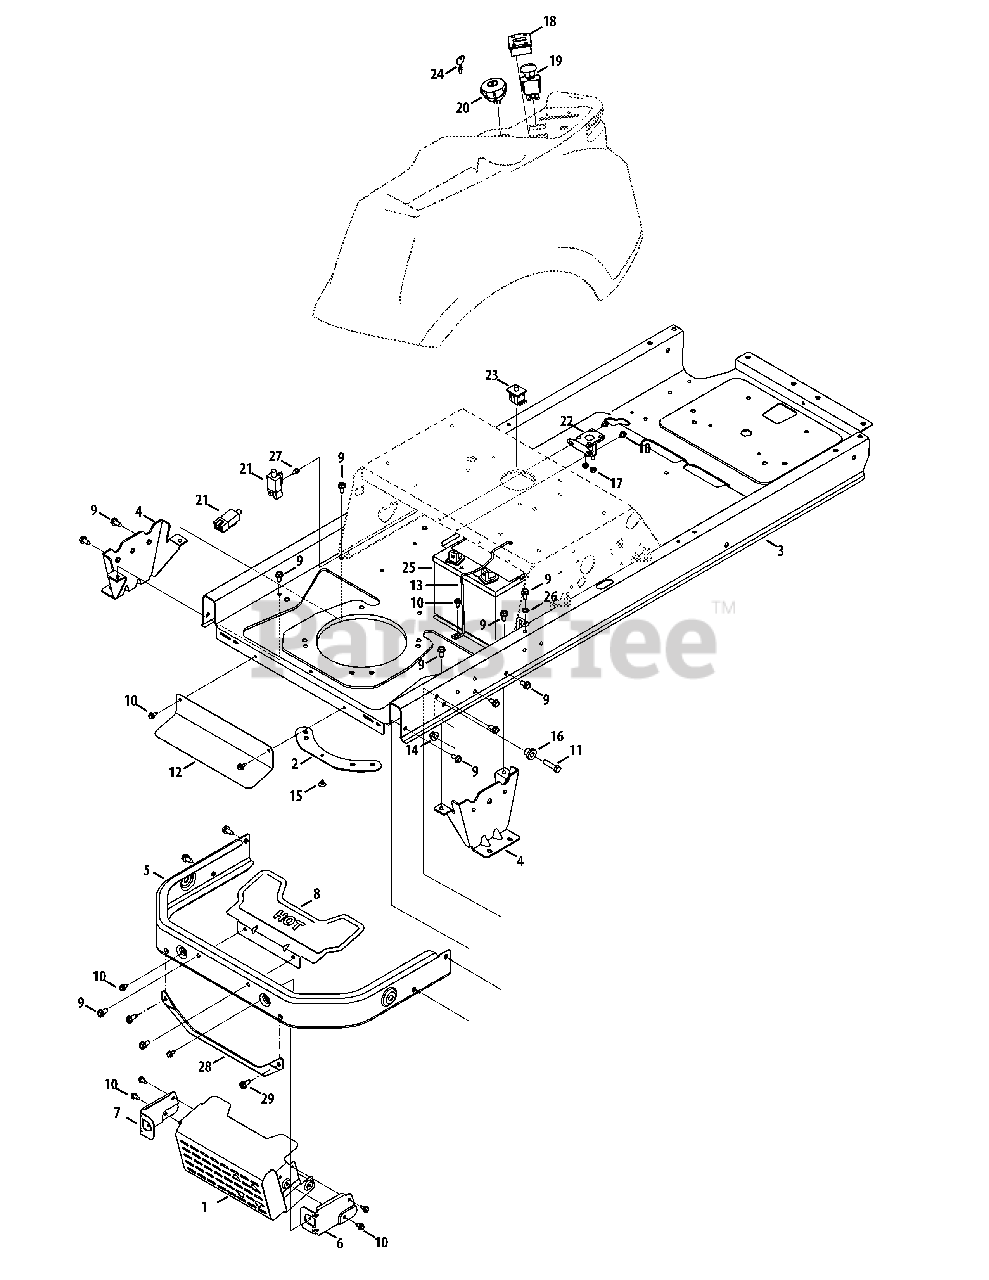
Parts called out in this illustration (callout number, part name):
1	Muffler Shield Assembly
2	Retainer Plate
3	Frame Assembly
4	Transmission Mounting Bracket
5	Rear Bumper
6	Muffler Mounting Shield Bracket, RH
7	Muffler Mounting Shield Bracket, LH
8	Muffler Shield
9	Hex Washer Screw 5/16-18 x .750
10	Hex Washer Screw 1/4-20 x .625
11	Hex Screw 3/8-16 x 1.25
12	Lower Heat Shield
13	Battery Rod
14	Flange Lock Nut, 3/8-16
15	Clip .250 Dia. x .500 LG
16	Shoulder Spacer .38 x 1.0 x .70
17	Flange Lock Nut 1/4-20
18	Hour Meter/Service Minder
19	Electric PTO Switch
20	Key Switch
21	Interlock Switch
22	Solenoid
23	Seat Switch
24	Key
25	Battery
26	Lock Washer 5/16
27	Shoulder Screw #10-32 x .500
28	Muffler Shield Bracket
29	TT Screw 5/16-18 x .75
